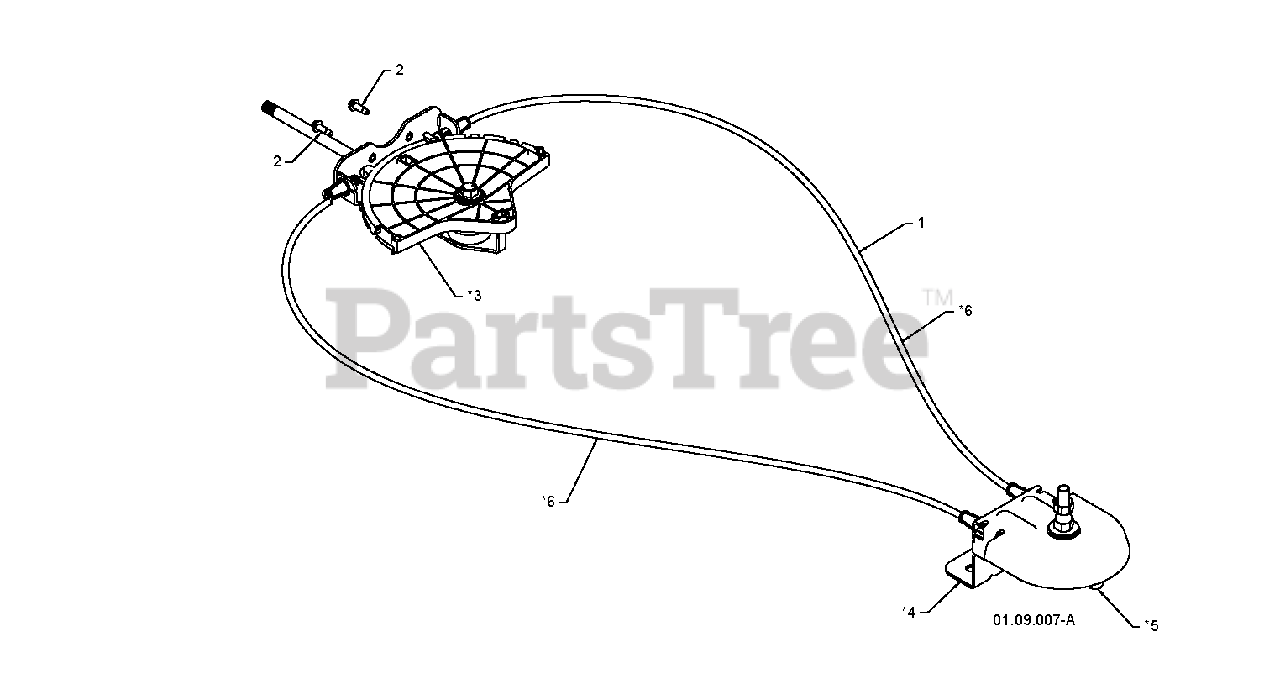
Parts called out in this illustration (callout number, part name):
1	LEVER/CABLE.ASM.ROTATOR
2	SCREW #10-24 X 5/8
3	CHUTE.ROT.HEAD.SERVICE
4	PIVOT.BRACKET
5	SNOW.PIVOT.PULLY
6	CABLE.ASSEMBLY
